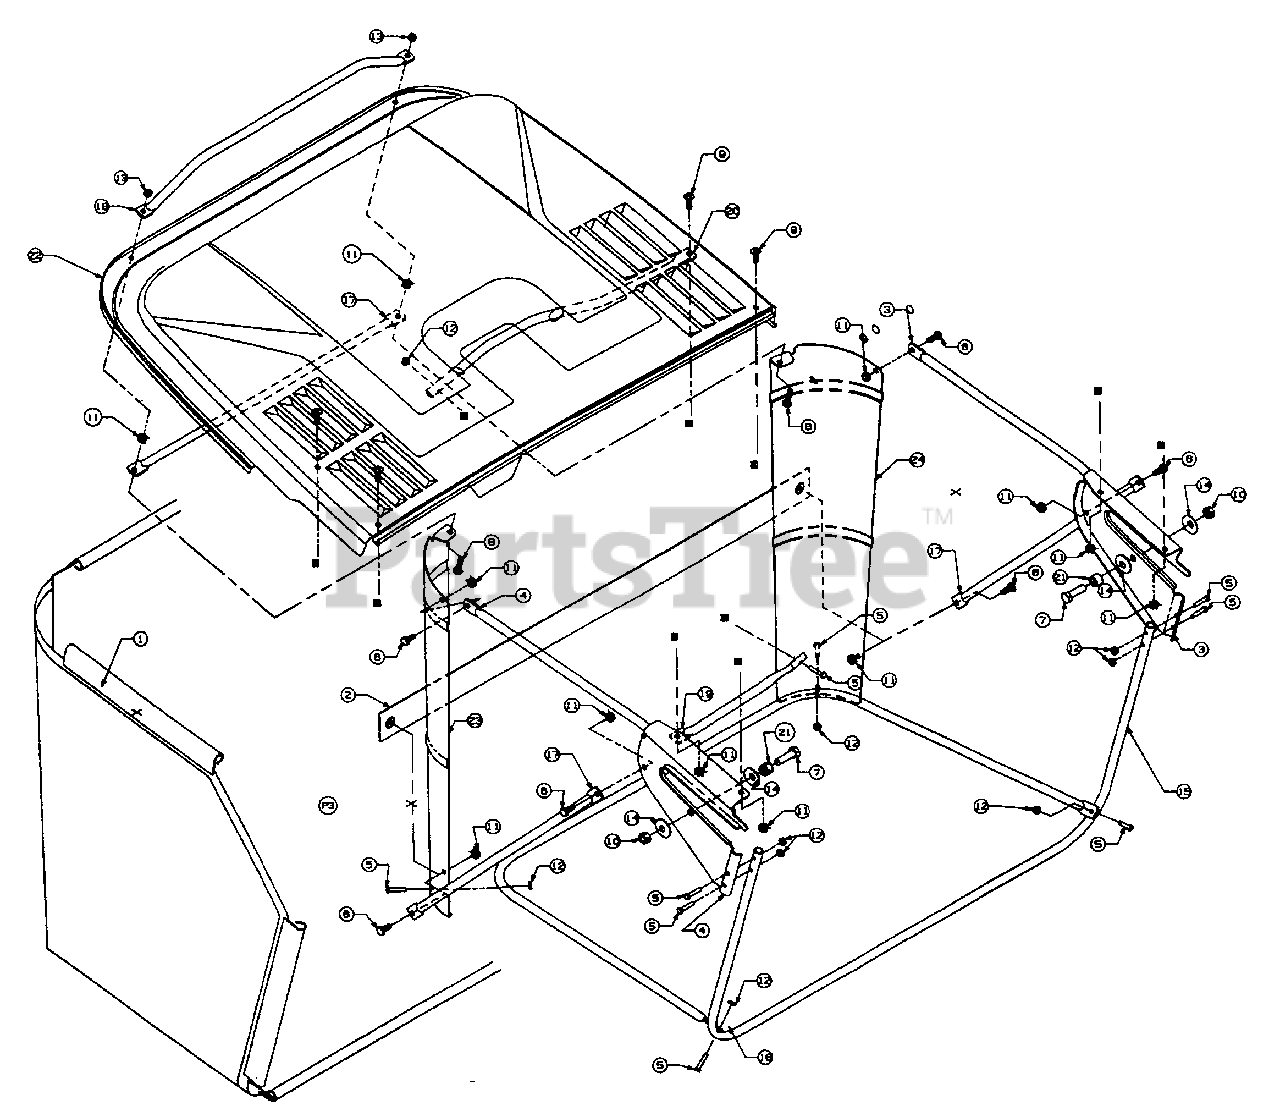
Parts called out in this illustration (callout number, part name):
1	Grass Bag
2	Strap Ass'y.
3	Grass Catcher Support Brkt. - L.H.
6	Hex Bolt 1/4-20 x .625" Lg.
7	Hex Bolt 3/8-16 x 1.25" Lg.
8	Hex Bolt 1/4-20 1" Lg.
9	Truss Mach. Scr. 1/4-20 x .75" Lg.
10	Hex Nut 3/8-16 Thd.
11	Hex Sems Nut 1/4-20 Thd.
12	Hex Sems Nut #10-24 Thd.
13	Hex Ins. L-Nut 1/4-20 Thd.
14	Bell-Wash. .39" I.D. x 1.13" O.D.
